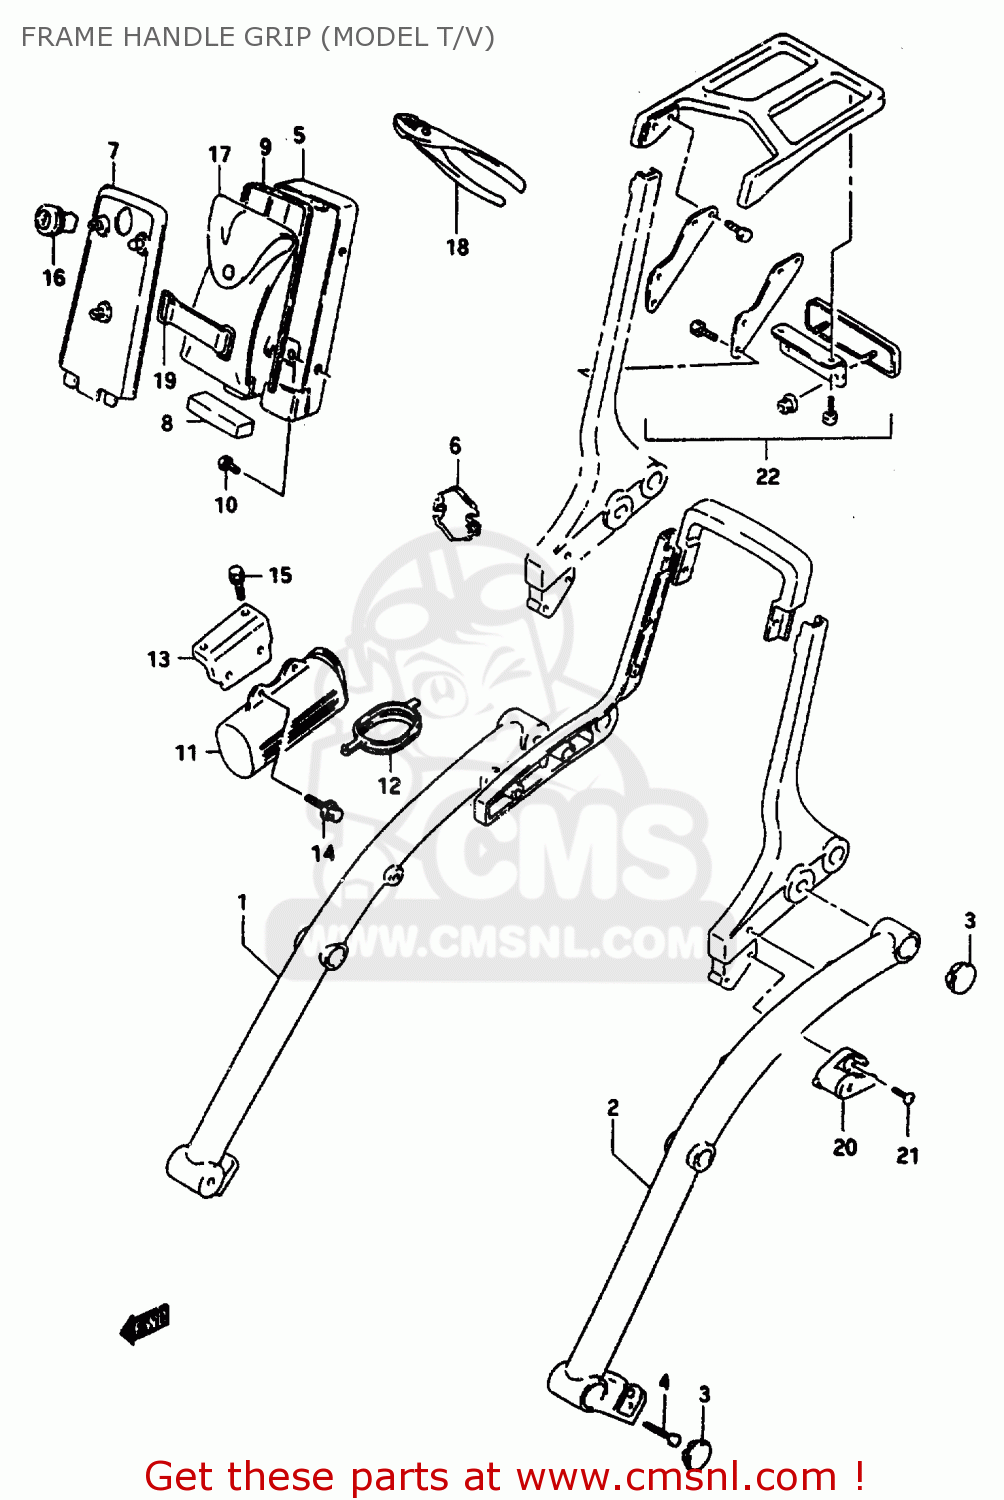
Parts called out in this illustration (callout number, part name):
1	GRIP,FRAME HANDLE RH
2	GRIP,FRAME HANDLE LH
3	CAP,FRAME HANDLE GRIP
4	BOLT
5	HOLDER,TOOL,REAR
6	EMBLEM,TOOL HOLDER RR
7	HOLDER,TOOL FR
8	CUSHION,TOOL BACK
9	MOLDING,TOOL HOLDER RR
10	BOLT
11	HOLDER,TOOL
12	CAP,HOLDER
13	PLATE, TOOL HOLDER
14	BOLT(6X16)
15	BOLT 6X16
16	LOCK SET,TOOL HOLDER
17	TOOL ASSY
18	PLIER(150)
19	BAND
20	LOCK SET,HELMET
21	SCREW
22	CARRIER SET,SPORT
23	CARRIER ASSEMBLY,REAR
